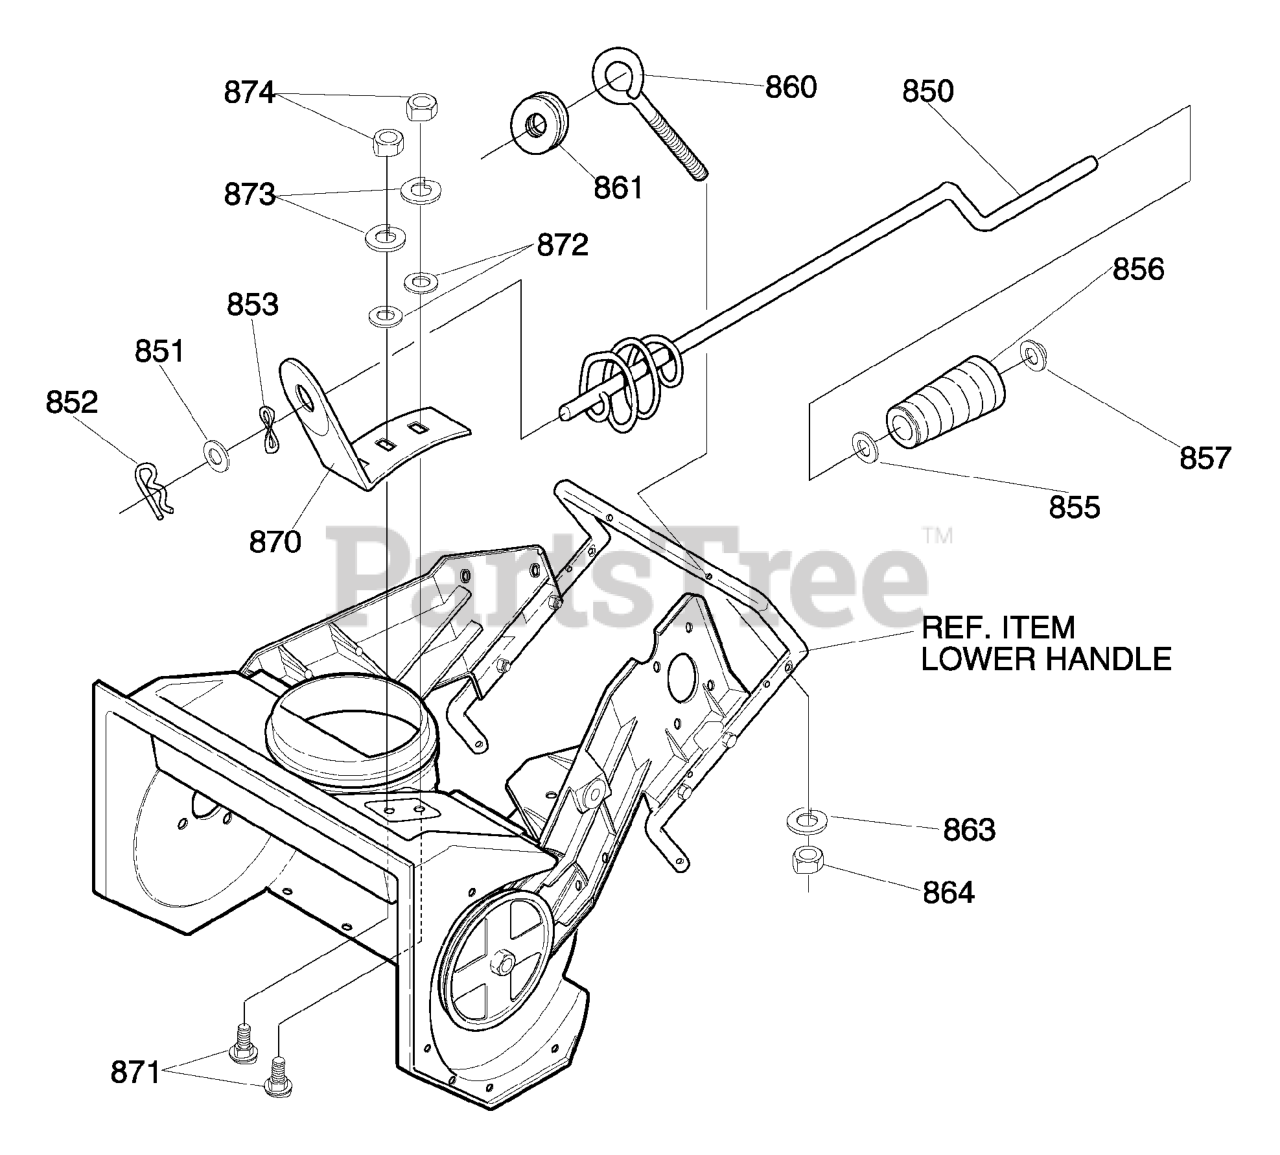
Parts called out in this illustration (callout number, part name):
850	ROD, ASSY UPPER CHUTE
851	FLATWASHER
852	COTTER PIN
853	WASHER, CURVED SPRING
855	FLATWASHER
856	KNOB, SLEEVE
857	NUT, PUSH
860	EYE BOLT 3/8-16x2.00
861	GROMMET, EYE BOLT
863	WASHER, SPLITLOCK
864	NUT, 3/8-16
870	BRACKET, CHUTE ROTATE
871	BOLT, 5/16-18 x .75
872	FLATWASHER
873	WASHER, SPTLOCK
874	NUT, 5/16-18
